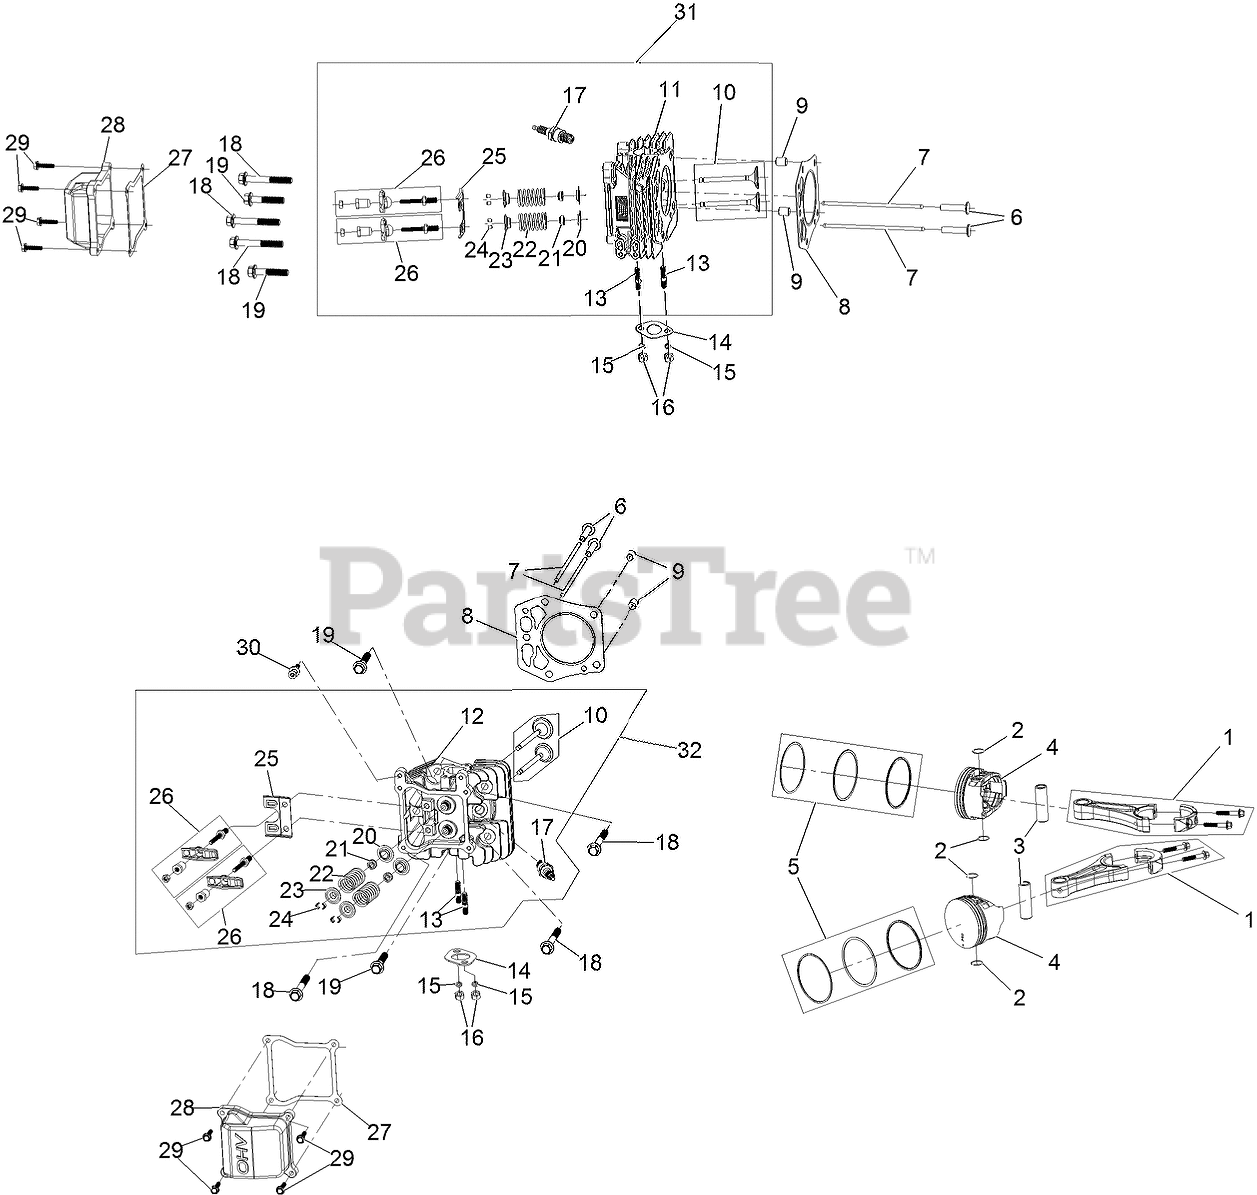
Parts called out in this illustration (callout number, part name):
1	CONNECTING ROD ASM
2	CLIP-PIN, PISTON
3	PIN-PISTON
4	PISTON
5	PISTON RING SET
6	LIFTER-VALVE
7	ROD-PUSH
8	GASKET-HEAD, CYLINDER
9	PIN-DOWEL
10	VALVE SET
11	HEAD-CYLINDER, RIGHT
12	HEAD-CYLINDER, LEFT
13	STUD-EXHAUST
14	GASKET-EXHAUST
15	WASHER-LOCK, SPLIT
16	NUT-HH
17	SPARK PLUG
18	SCREW-HWH
19	SCREW-HWH
20	SEAT-SPRING, VALVE
21	SEAL-STEM, VALVE
22	SPRING-VALVE
23	RETAINER-SPRING, VALVE
24	KEEPER-VALVE
25	PLATE-GUIDE, PUSH ROD
26	ROCKER ARM ASM
27	GASKET-VALVE COVER
28	COVER-VALVE
29	SCREW-HHF
30	SCREW-SHOULDER, HH
31	RIGHT HEAD ASM
32	LEFT HEAD ASM
